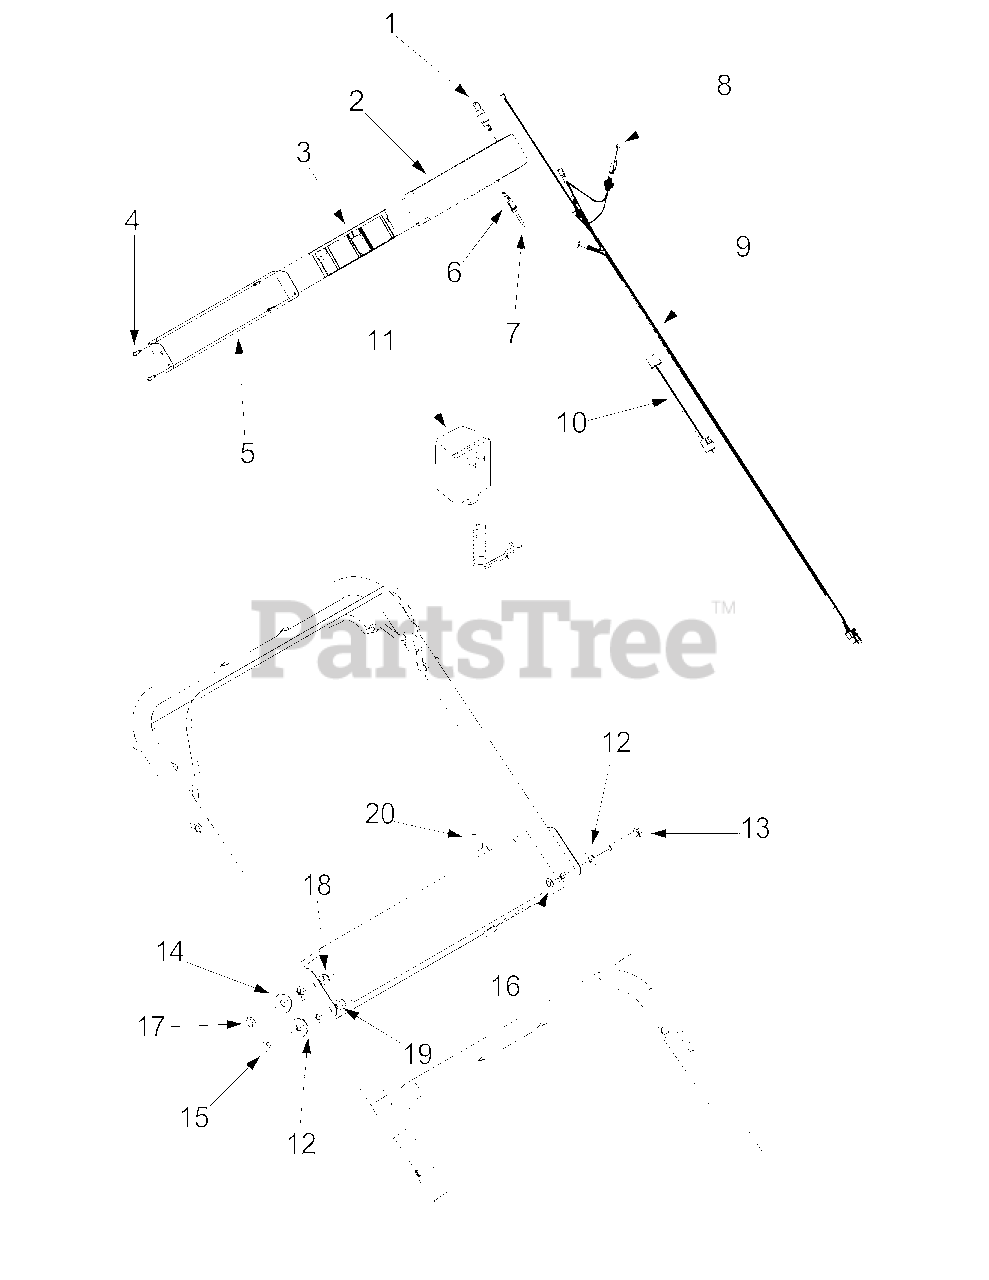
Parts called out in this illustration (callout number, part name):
1	Key Switch
2	Upper Battery Tray
3	Battery 12V
4	Screw #12-16 x 1.0
7	Fuse 7.5 Amp
8	Plug
9	Electric Start Harness
10	Harness Extension
11	Battery Charger
12	Bell Washer.265 ID x.75 OD
13	Hex Cap Screw 1/4-20 x 1.75
14	Bell Washer.340 x.872 x.060
15	Screw 1/4-20 x 1.25
16	Hex Lock Nut 1/4-20
17	Curved Carr. Bolt 5/16 x 1.5
18	Hex Nut 5/16-18
19	Hex Nut 1/4-20
20	Ignition Key
